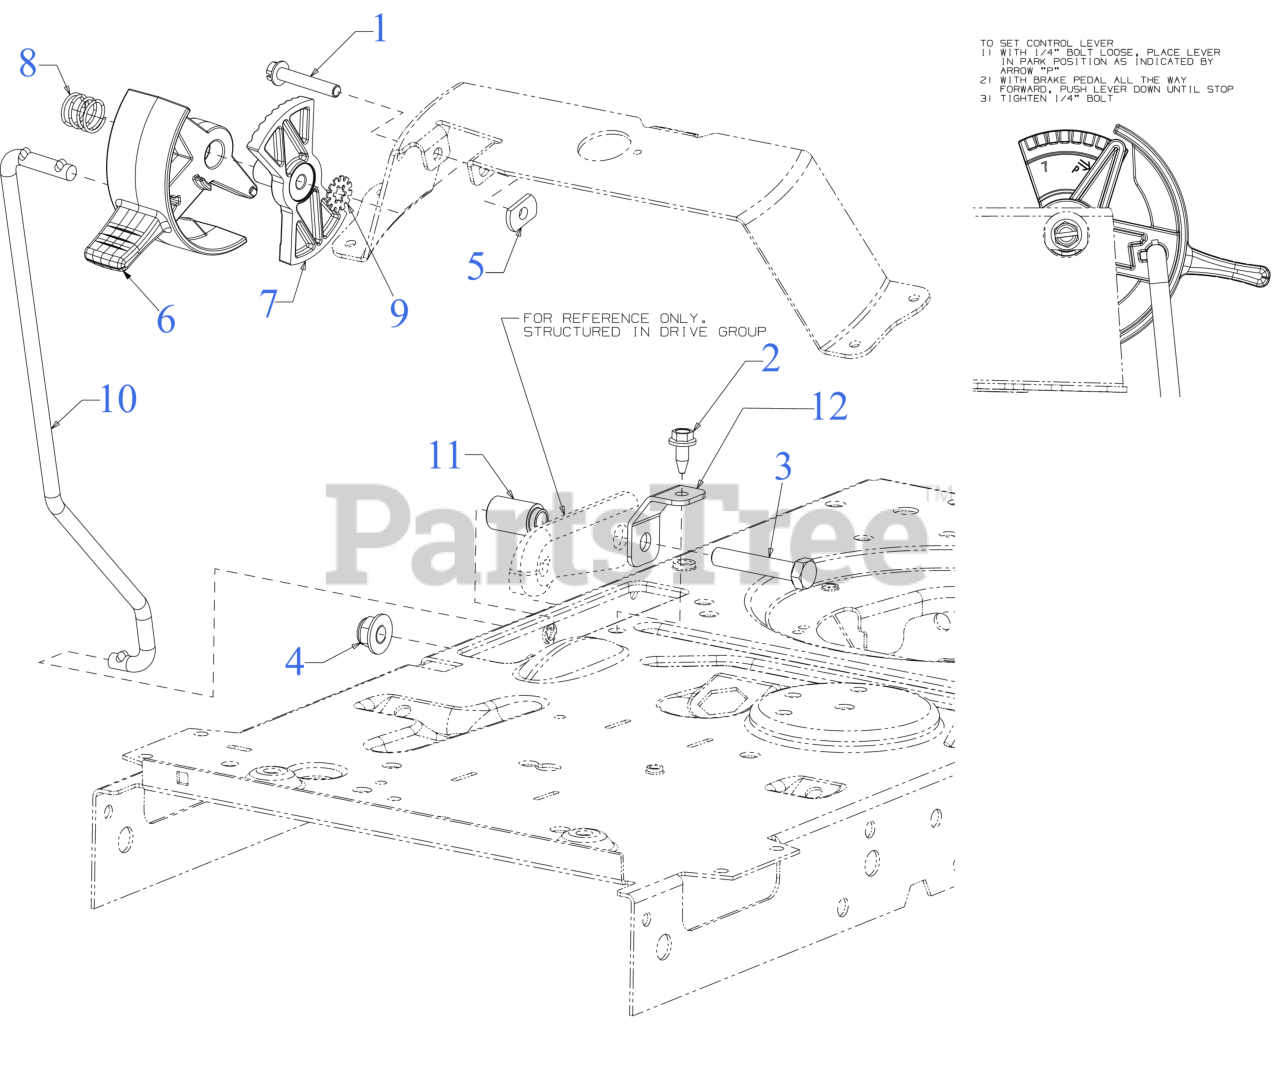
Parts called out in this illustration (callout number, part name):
1	HEX FLANGE BOLT 1/4-20 x 1.5
2	SCREW 1/4-20X.625
3	SCREW 3/8-16 x 2.0 GR 8
5	FLAT NUT
6	SHIFT LEVER
7	INDEX CONTROL 7SPEED
8	COMPRESSION SPRING
9	WASHER
10	SPEED CONTROL ROD
11	FLANGE SPACER
12	SPEED LATCH TAB
